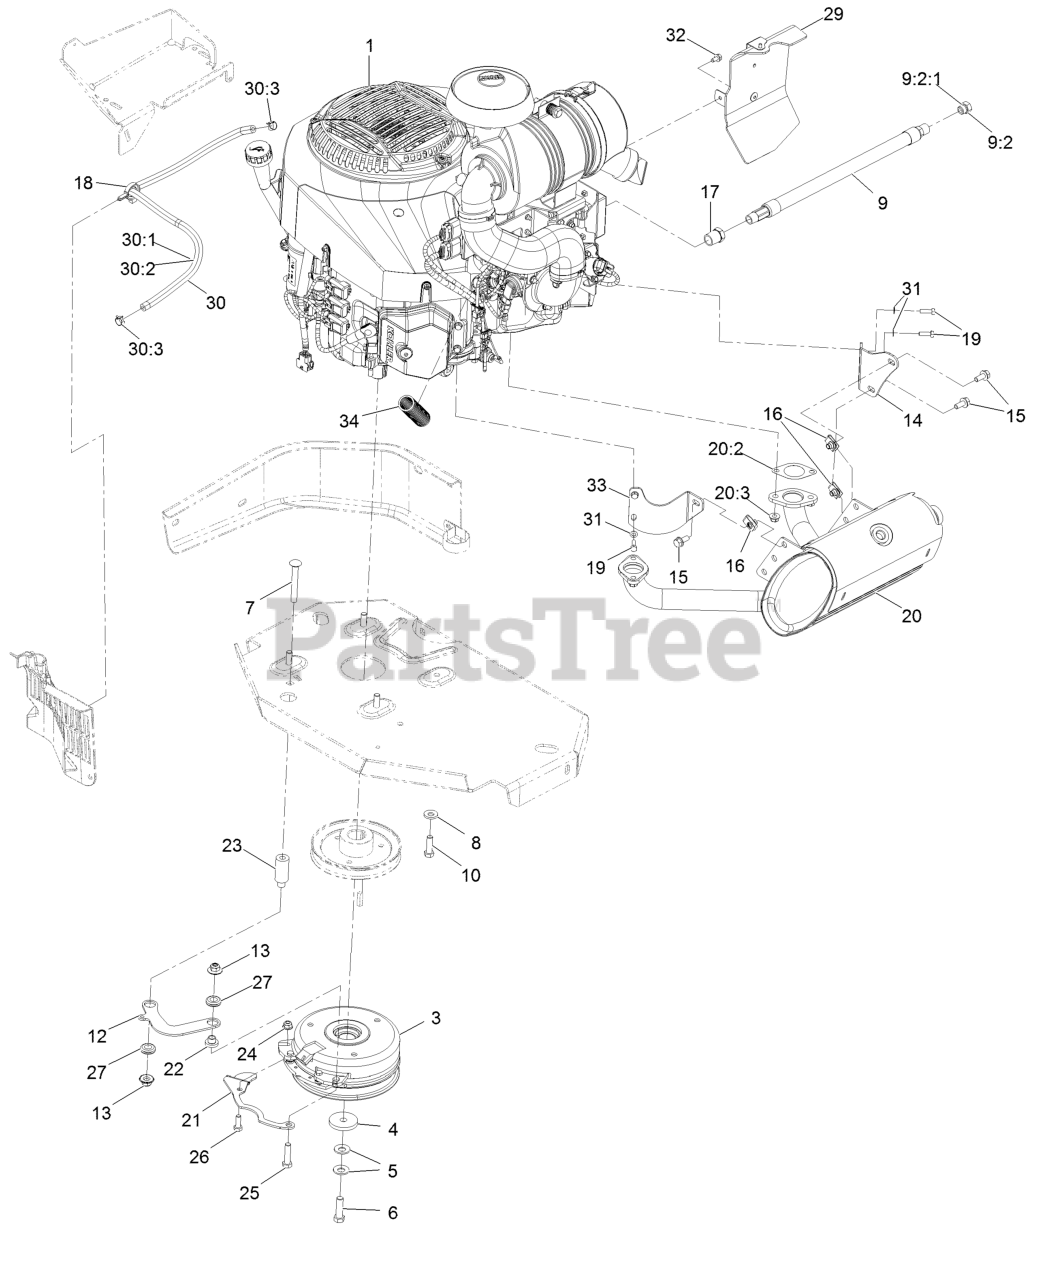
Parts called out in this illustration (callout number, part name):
3	Clutch, Cms250
3	Clutch Kit
4	Washer-Clutch
5	Washer-Spring Disc 7/16
6	Screw-HH 7/16-20 X 1 1/2 W/Loctite
7	Bolt-Carriage 3/8-16 X 3
8	Washer-Spring Disc 3/8
9	Oil Drain Hose ASM
9:2	Plug-W/O-Ring
9:2:1	O-Ring
10	Screw-HH 3/8-16 X 1 1/4
12	Link-Anchor, Clutch
13	Nut-Nyloc 3/8-16 Flg
14	Bracket-Muffler
15	Screw-HH Flg 5/16-18 X 3/4
17	Bushing
18	Clamp-Hose
19	Screw-HH M6-1 X 20Mm W/Patch
20	Muffler-940-980 Koh Efi
20	Muffler-Kit
20:2	Gasket-Exhaust
20:3	Nut-Flange, Lock
21	Belt-Guide
24	Nut-Nyloc 5/16-18 Flg
25	Screw-HH 3/8-16 X 1 1/2
26	Screw-HH 5/16-18 X 7/8
27	Grommet-Rubber
29	Rear Baffle ASM
30	ASM, Fuel Line
30:1	Hose-Fuel Line 29"
30:2	Sleeve, Thermal
30:3	Clamp-Hose
31	Washer-Spring Disc 1/4
32	Screw-HWH M6-1 X 12Mm Tf
33	Bracket-Muffler, Front
34	Conduit-Convoluted
